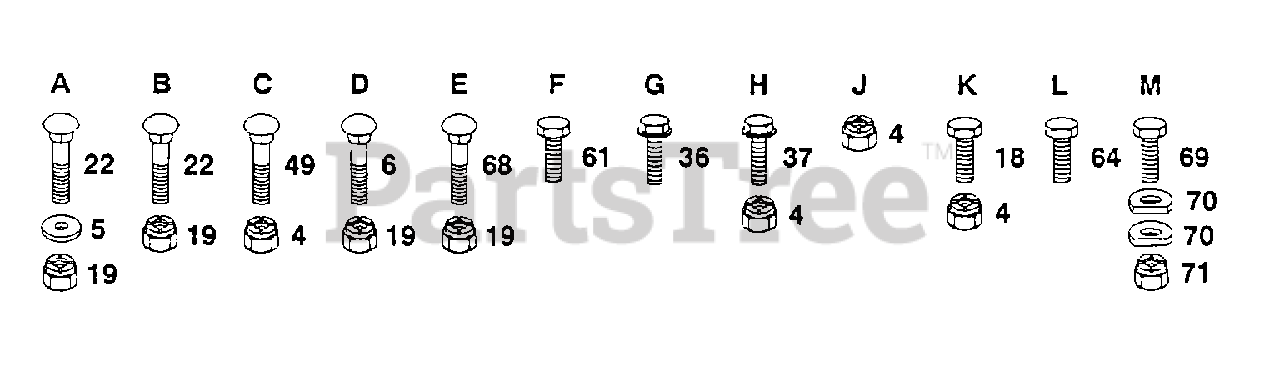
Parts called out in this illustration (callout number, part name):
5	WASHER M
6	BOLT
22	BOLT
36	SCREW
37	SCREW
49	BOLT
61	BOLT
64	BOLT.3/8-14X1.25
69	BOLT LT
70	WASHER T
